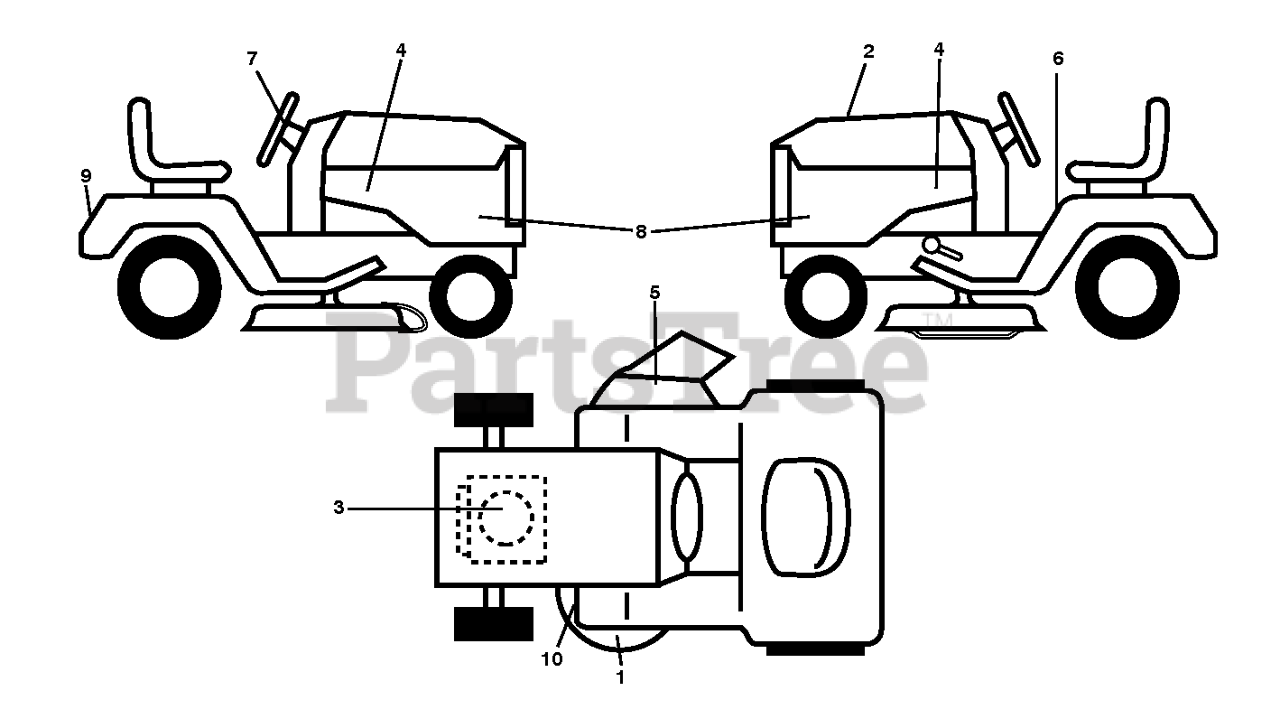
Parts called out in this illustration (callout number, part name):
1	DECAL.PPRO.10YRDECKWAR.POP
2	DECAL.BYPASS.FENDER.CRD/LT/YT
3	DECAL.ENG.BS.19INTK.DOM.381714
4	DECAL.POULAN PRO.YEL/BLK.2017
5	DECAL, DECK DEFLECTOR, WARNING
6	DECAL.FENDER.WARNING.ENGLISH
7	DECAL.STRWHL.STDSQ.PPRO.YEL.17
9	DECAL.REARFNDR.LOGO.BLK.2017
10	DECAL.V-BELT.SCH.42/46"MEC/ELE
